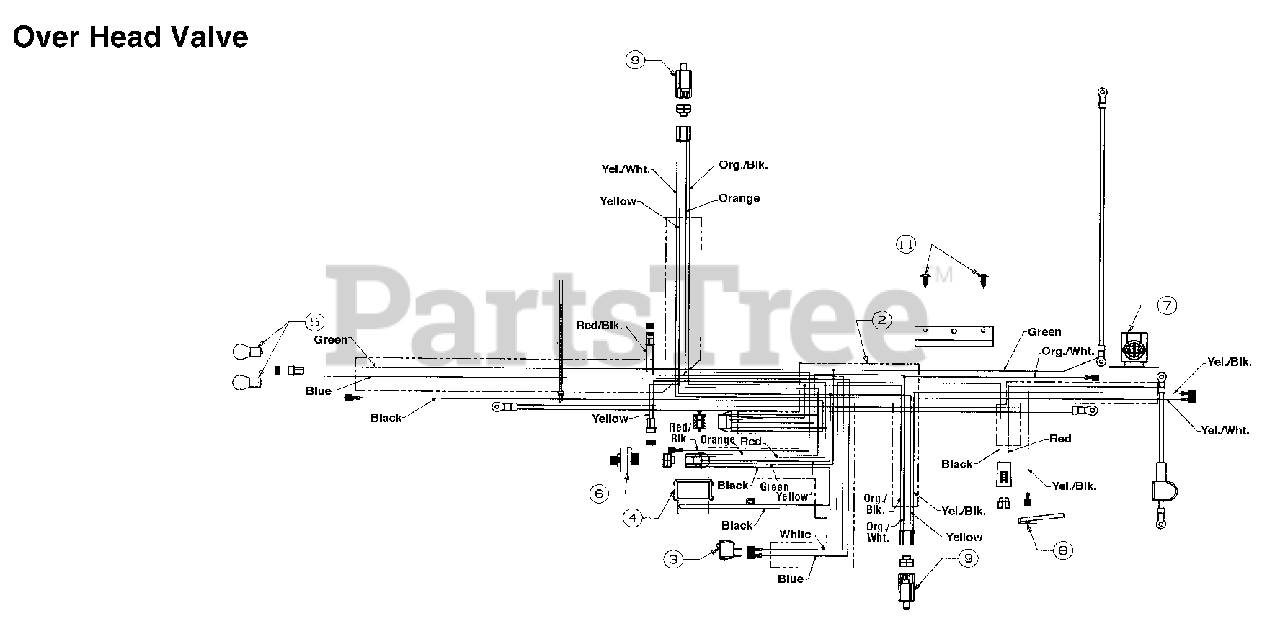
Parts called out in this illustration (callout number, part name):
2	Light Switch
3	Ammeter
4	Bulb
5	Ignition Switch
6	Solenoid
7	Safety Switch (Reverse)
8	Safety Switch
